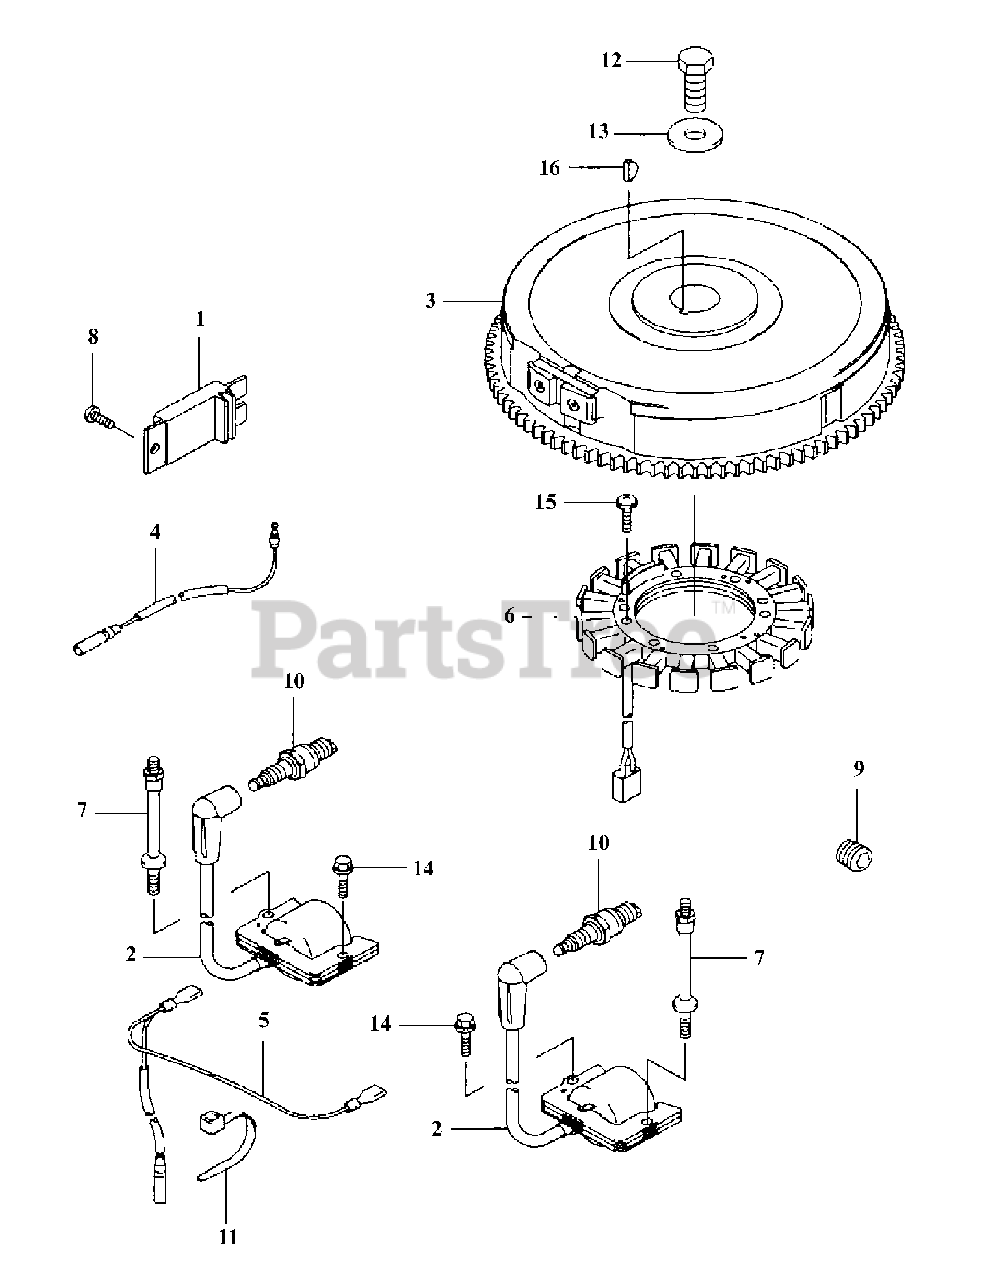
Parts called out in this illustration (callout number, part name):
1	Regulator-Voltage
2	Coil-Assy-Ignition
3	Flywheel-Assy
4	Wire-Lead 540mm
6	Coil-Carging
7	Stud
10	Plug-Spark
15	Screw-Pan-wp-cros
16	Key-Woodruff
